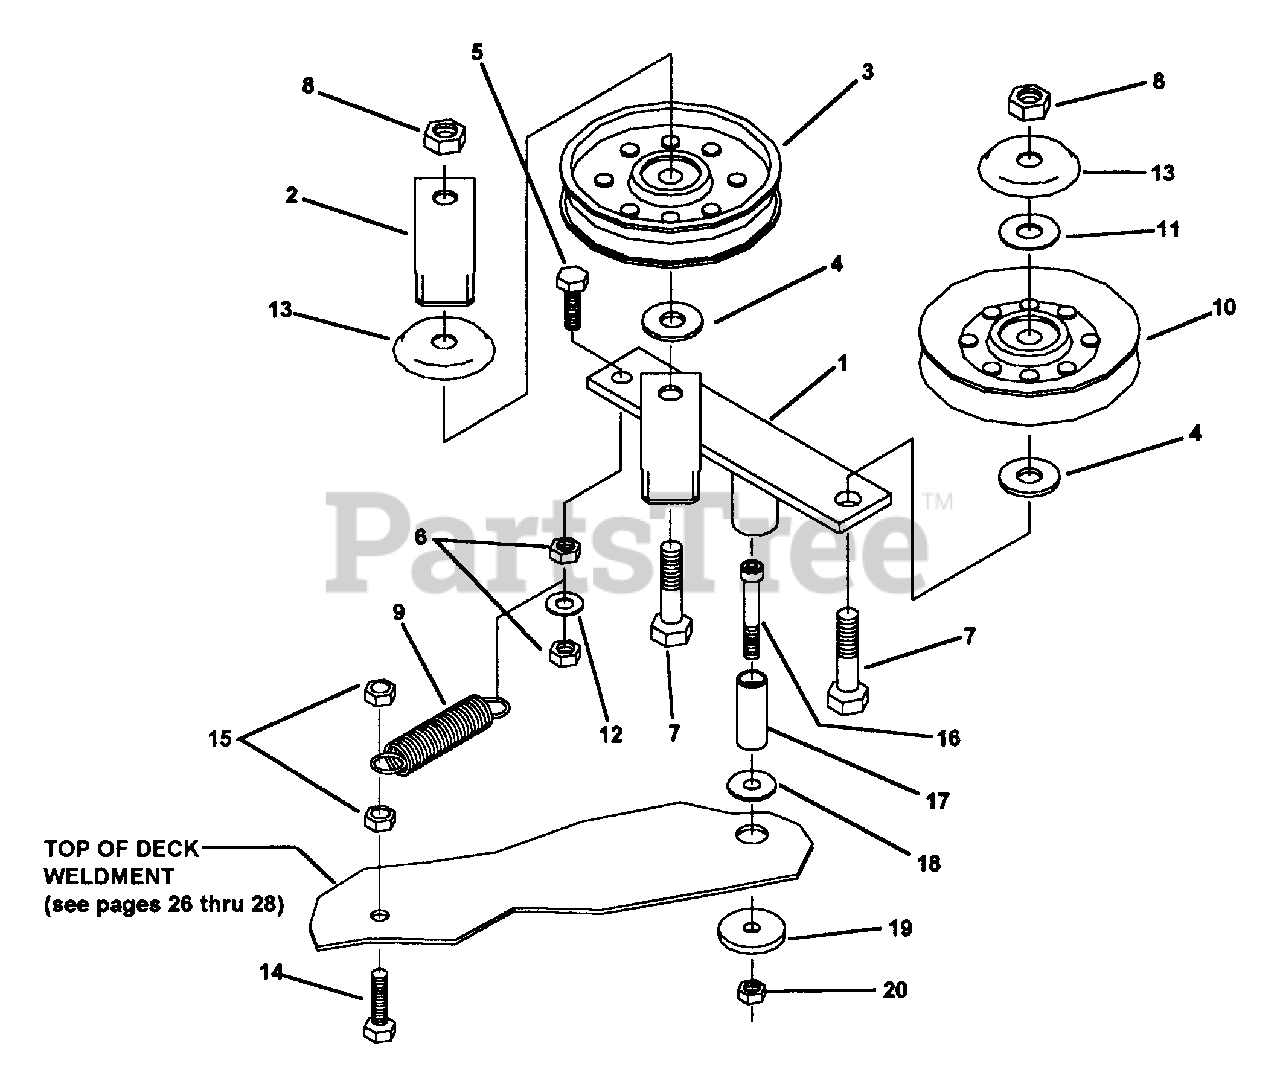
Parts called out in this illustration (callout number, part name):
1	DOUBLE IDLER WELDMENT (w/bushing)
2	PLATE, BELT STOP
3	PULLEY, FLAT IDLER, 1/2" BORE, 4" O.D.
4	WASHER, FLAT STD. 1/2"
5	BOLT, 3/8-24 X 1-1/4" GR. 5
6	LOCKNUT, HEX. 3/8"-24 YZ GR5
7	BOLT, 1/2-13 X 2", GR.5
8	NUT, 1/2-13, STOVER
9	SPRING, EXTENSION, 3/4 X 4" O.A.L.
10	PULLEY, V-IDLER, 1/2 BORE, 4-3/8 O.D.
11	WASHER, 1/2 TYPE B NARROW
12	WASHER, FLAT STD. 3/8
13	WASHER, BEARING CAP
14	BOLT, 3/8-24 X 1-1/4" GR.5
15	LOCKNUT, HEX. 3/8"-24 YZ GR5
16	CAPSCREW, SOCKET HEAD 5/16"-18 X 2 1/4, GR 8
17	IDLER MOUNTING PIN
18	BUSHING, IDLER PIN MTG.
20	LOCKNUT, 5/16-18 STOVER
